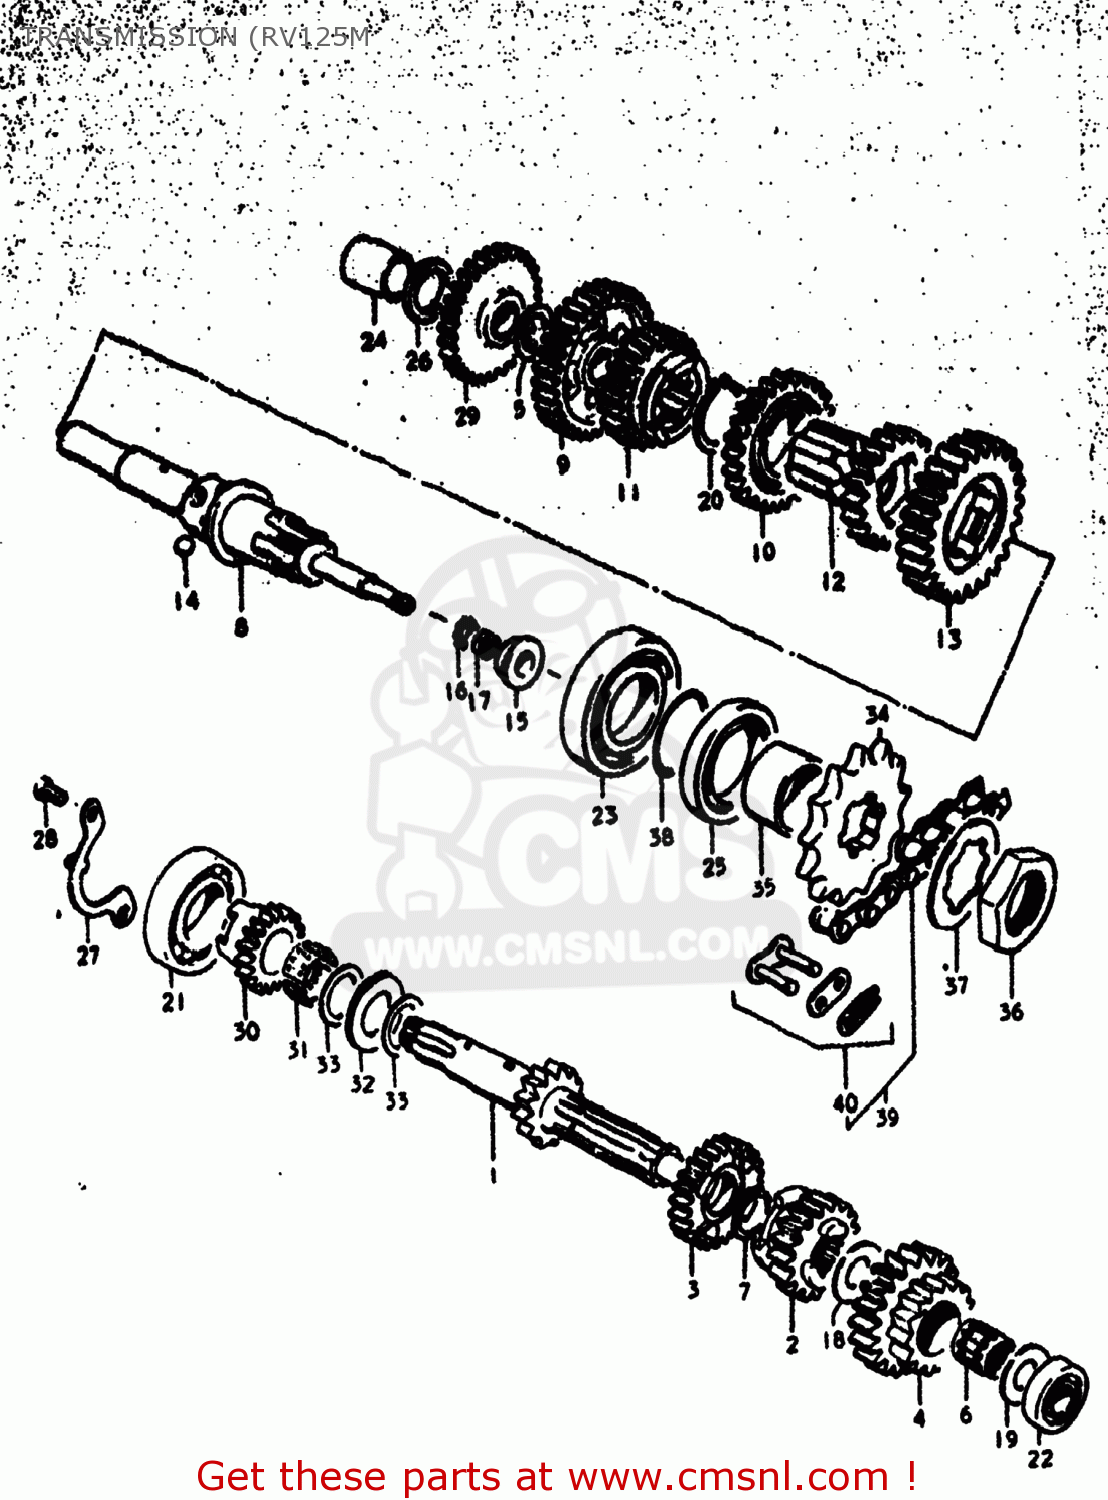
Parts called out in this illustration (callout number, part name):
1	SHAFT,COUNTER
2	GEAR,SECOND DRIVE
3	GEAR,THIRD DRIVE
4	GEAR,FOURTH DRIVE
5	WASHER,THRUST
6	ROLLER BEARING (15X19X1
7	CIRCLIP
8	SHAFT,DRIVE
9	GEAR,FIRST DRIVEN
10	GEAR,SECOND DRIVEN
11	GEAR,THIRD DRIVEN
12	GEAR,FOURTH DRIVEN
14	BALL
15	OIL SEAL
16	LOCK WASHER
17	NUT
18	WASHER,THRUST
19	WASHER
20	CIRCLIP
21	BEARING, RH
22	BEARING
23	BEARING
24	BUSHING
25	SEAL,OIL(30X44X6)
26	WASHER
27	RETAINER,CNTR SHAFT BEARING
28	SCREW
29	GEAR,KICK STARTER IDLE
30	GEAR,KICK STARTER DRIVE
31	BEARING(19.2X23.2X19)
32	BEARING(21X32X2.85)
33	WASHER(21X30X0.8)
34	SPROCKET,ENGINE
35	SPACER (25X30X12.4)
36	NUT
37	WASHER,LOCK
38	O RING(D:1,ID:24.5)
39	CHAIN ASSEMBLY,DRIVE
40	JOINT ASSEMBLY,CHAIN
